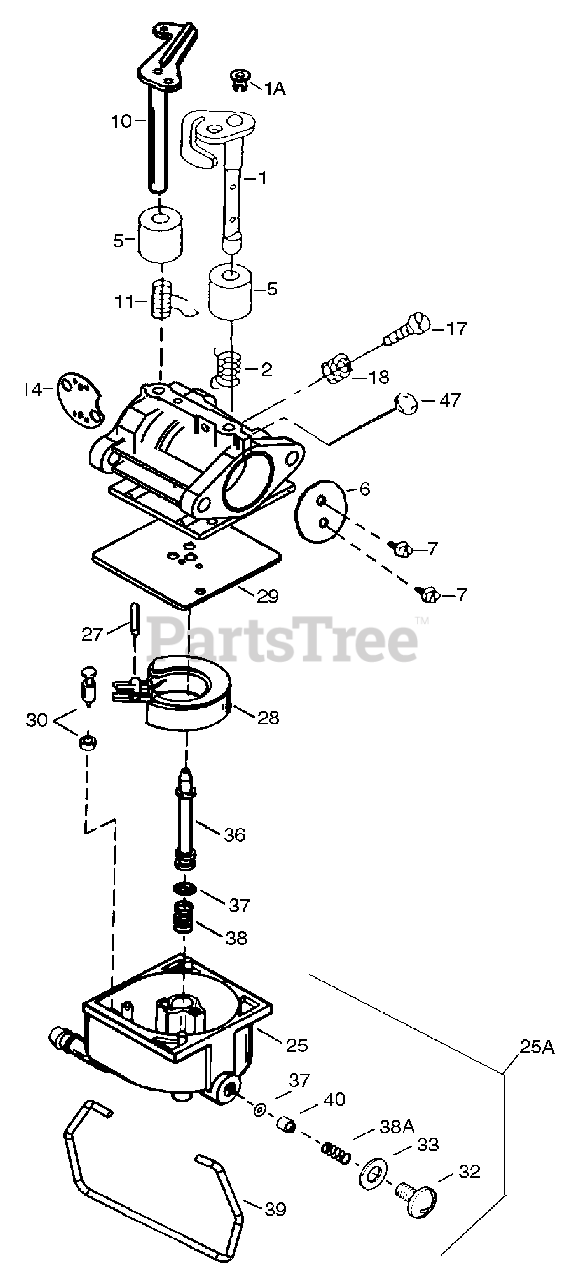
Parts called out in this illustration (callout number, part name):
1	Throttle Shaft & Lever Assembly
1A	Throttle Link Bushing
2	Throttle Return Spring
6	Throttle Shutter
7	Throttle Shutter Screws
10	Choke Shaft & Lever Assembly
11	Choke Return Spring
14	Choke Shutter
17	Throttle Crack Screw/Idle Speed Screw
18	Tension Spring
25	Float Bowl Assembly
25A	Bowl Kit
29	Float Bowl to Body Gasket
30	Inlet Needle & Seat
32	Bowl Drain Screw
33	Bowl Drain Washer
36	Main Nozzle Tube
37	O-Ring
38	Spring, Main Nozzle Tube
39	Float Bowl Retainer
40	Main Fuel Jet
47	Welch Plug, Idle Mixing Well
